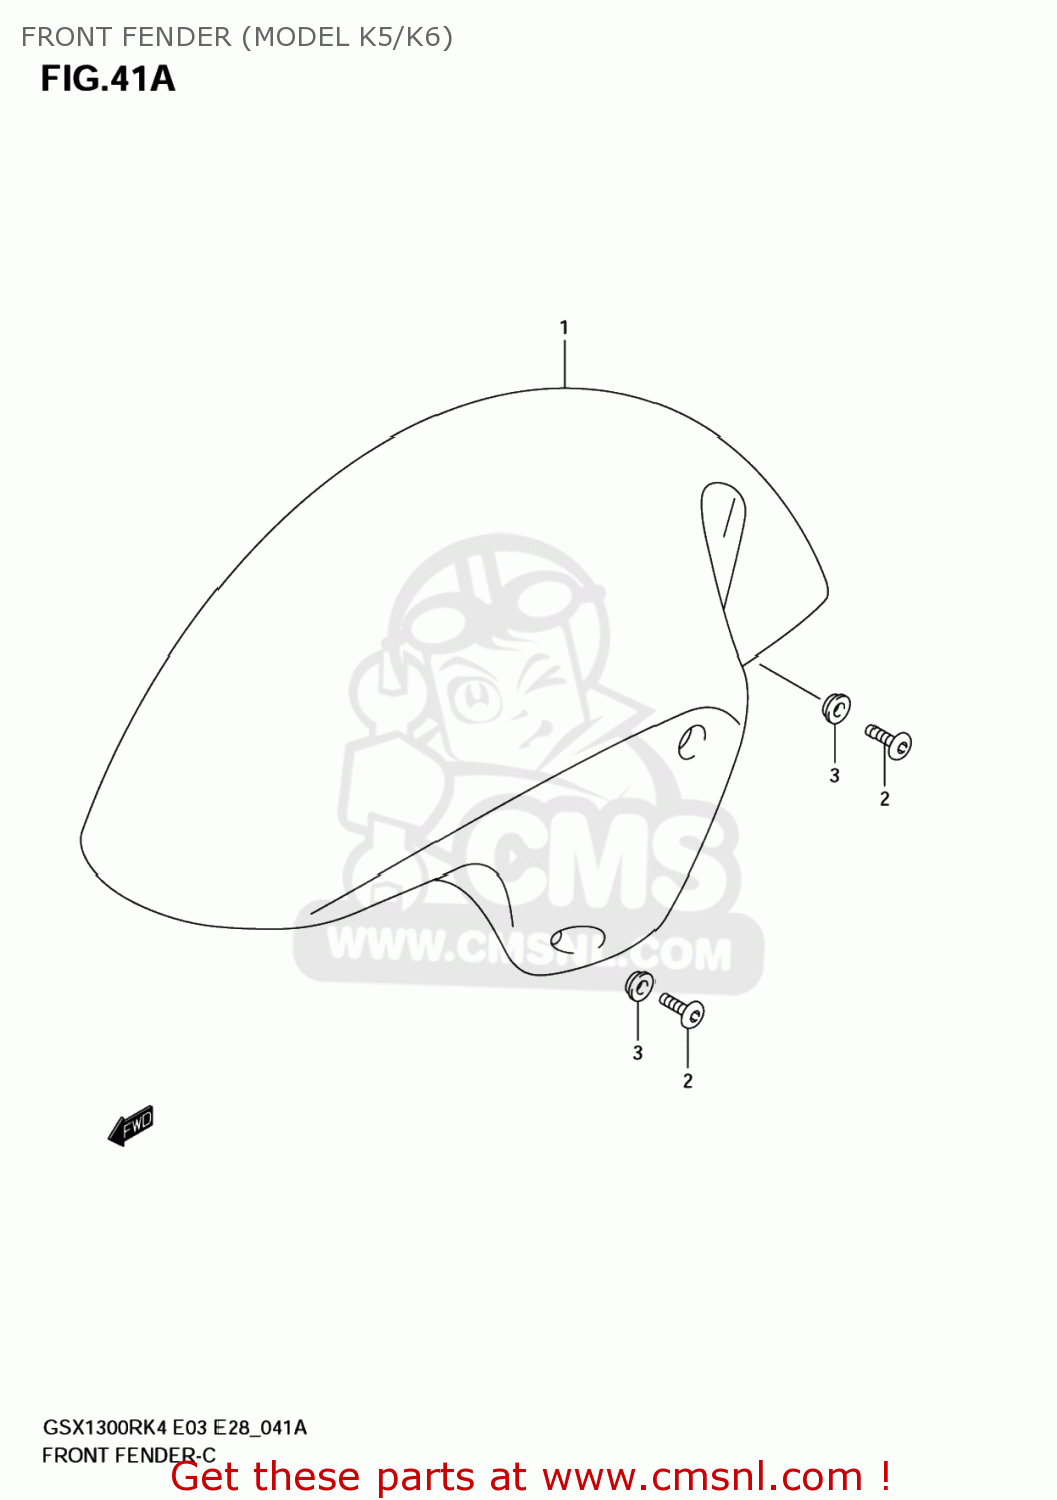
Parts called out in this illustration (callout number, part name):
1	FENDER,FR
2	SCREW(6X16)
3	WASHER(6.3X16X1.5)
